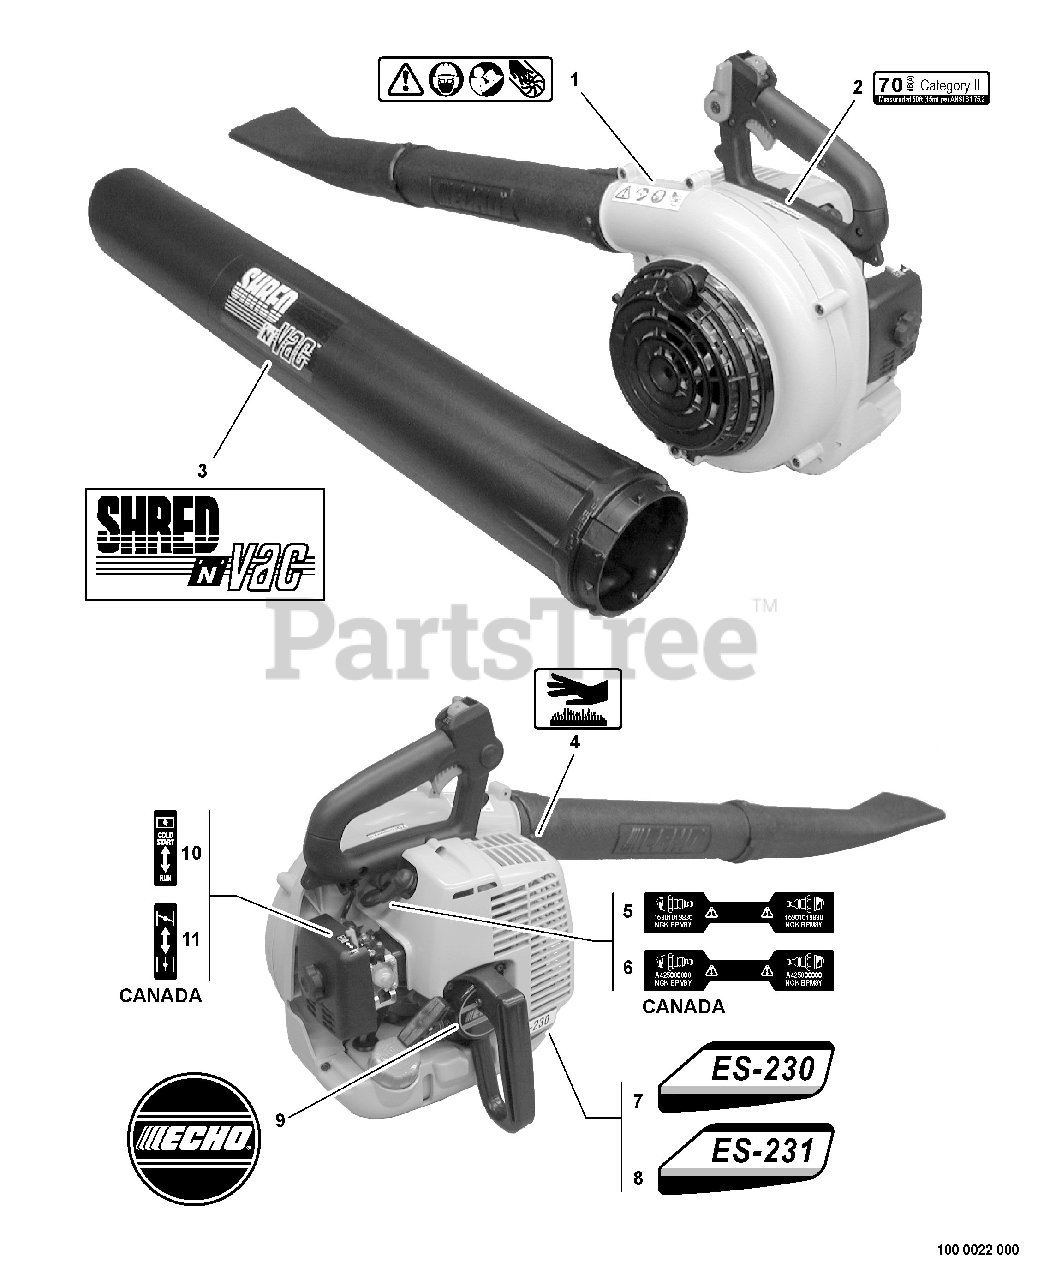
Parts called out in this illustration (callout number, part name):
1	LABEL - CAUTION
2	LABEL - NOISE 70dB(A) CAT II
3	LABEL - SHRED 'N' VAC
4	LABEL - HOT SURFACE
5	LABEL - SPARK PLUG -- BPM-8Y
6	LABEL - SPARK PLUG -- BPMR-8Y
7	LABEL - MODEL ES-230
8	LABEL - MODEL ES-231
9	LABEL - ECHO
10	LABEL - CHOKE
11	LABEL - CHOKE
